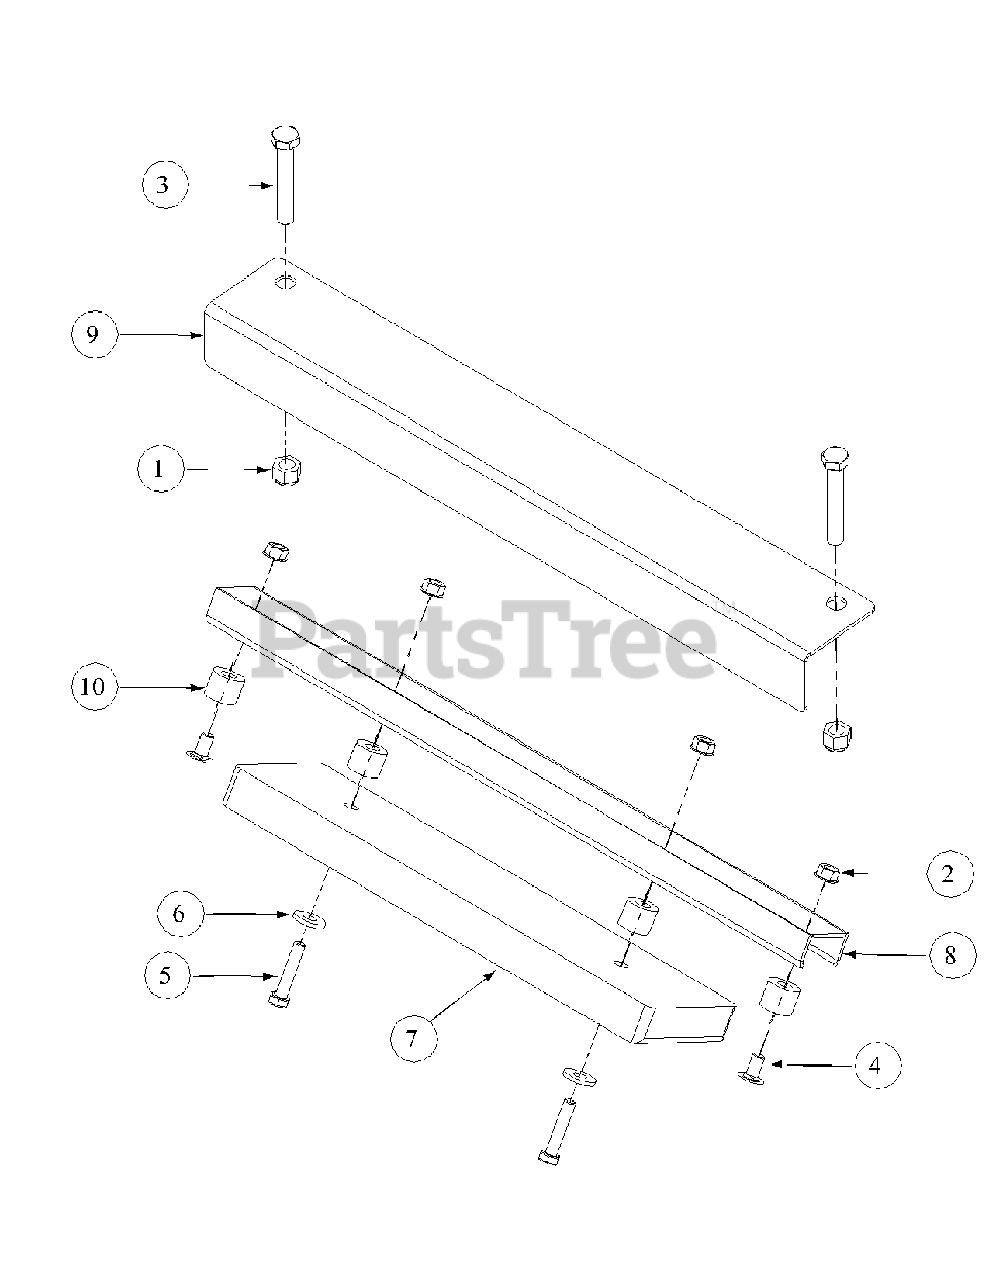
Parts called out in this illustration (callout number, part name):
1	Hex Nut, 1/2-13, Insert Lock
2	Nut, Hex 3/8-16 Flange Lock
3	HHCS, 1/2-13, 3.00
4	Carriage Bolt, 3/8-16 x 1.75
5	Hex Cap Screw, 3/8-16, 3.00
6	Flat Washer, .406 ID x 1.0 OD x .105
7	Bar Weight
8	Bumper Cross Bar
9	Rear Bumper Bracket
10	Spacer .635 ID x .86 LG
